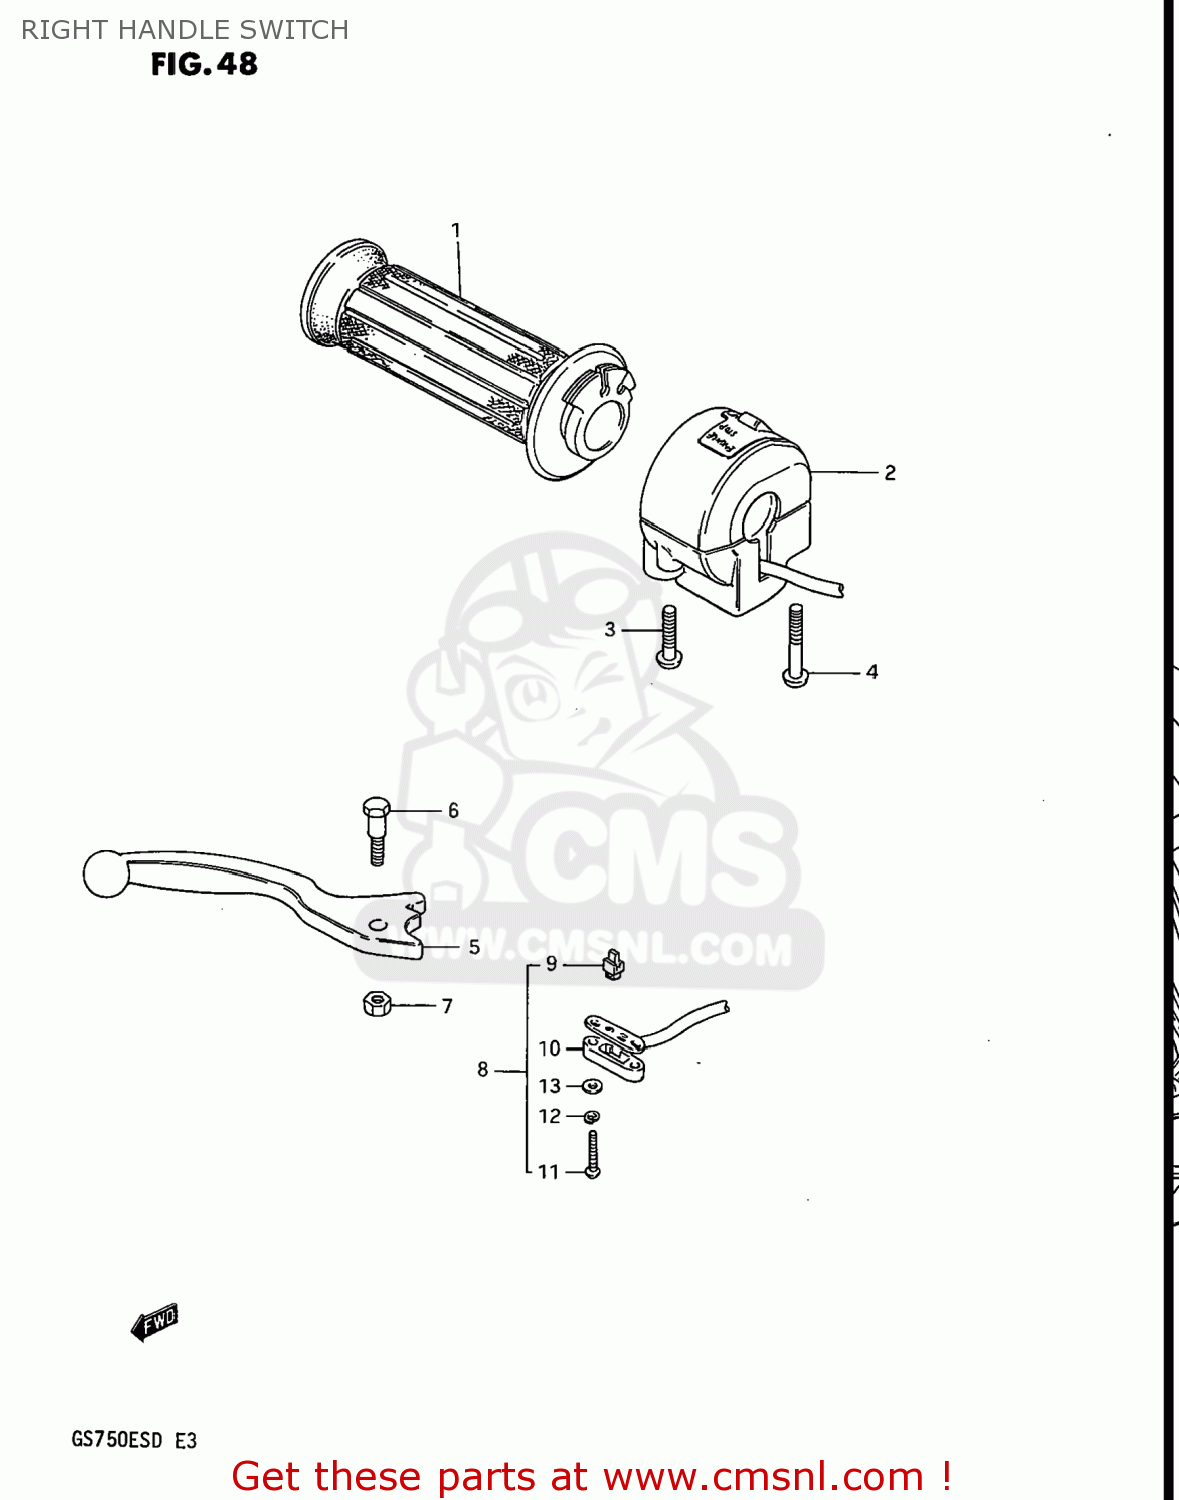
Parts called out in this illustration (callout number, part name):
1	GRIP,THROTTLE
2	SWITCH ASSEMBLY,HANDLE,RIGHT
3	SCREW
4	SCREW
5	LEVER,BRAKE
6	BOLT
7	NUT 6MM
8	SWITCH ASSEMBLY
9	CONTACT,SWITCH
10	COVER,FR BK TERMINAL BASE
11	SCREW
12	LOCK WASHER
13	WASHER
